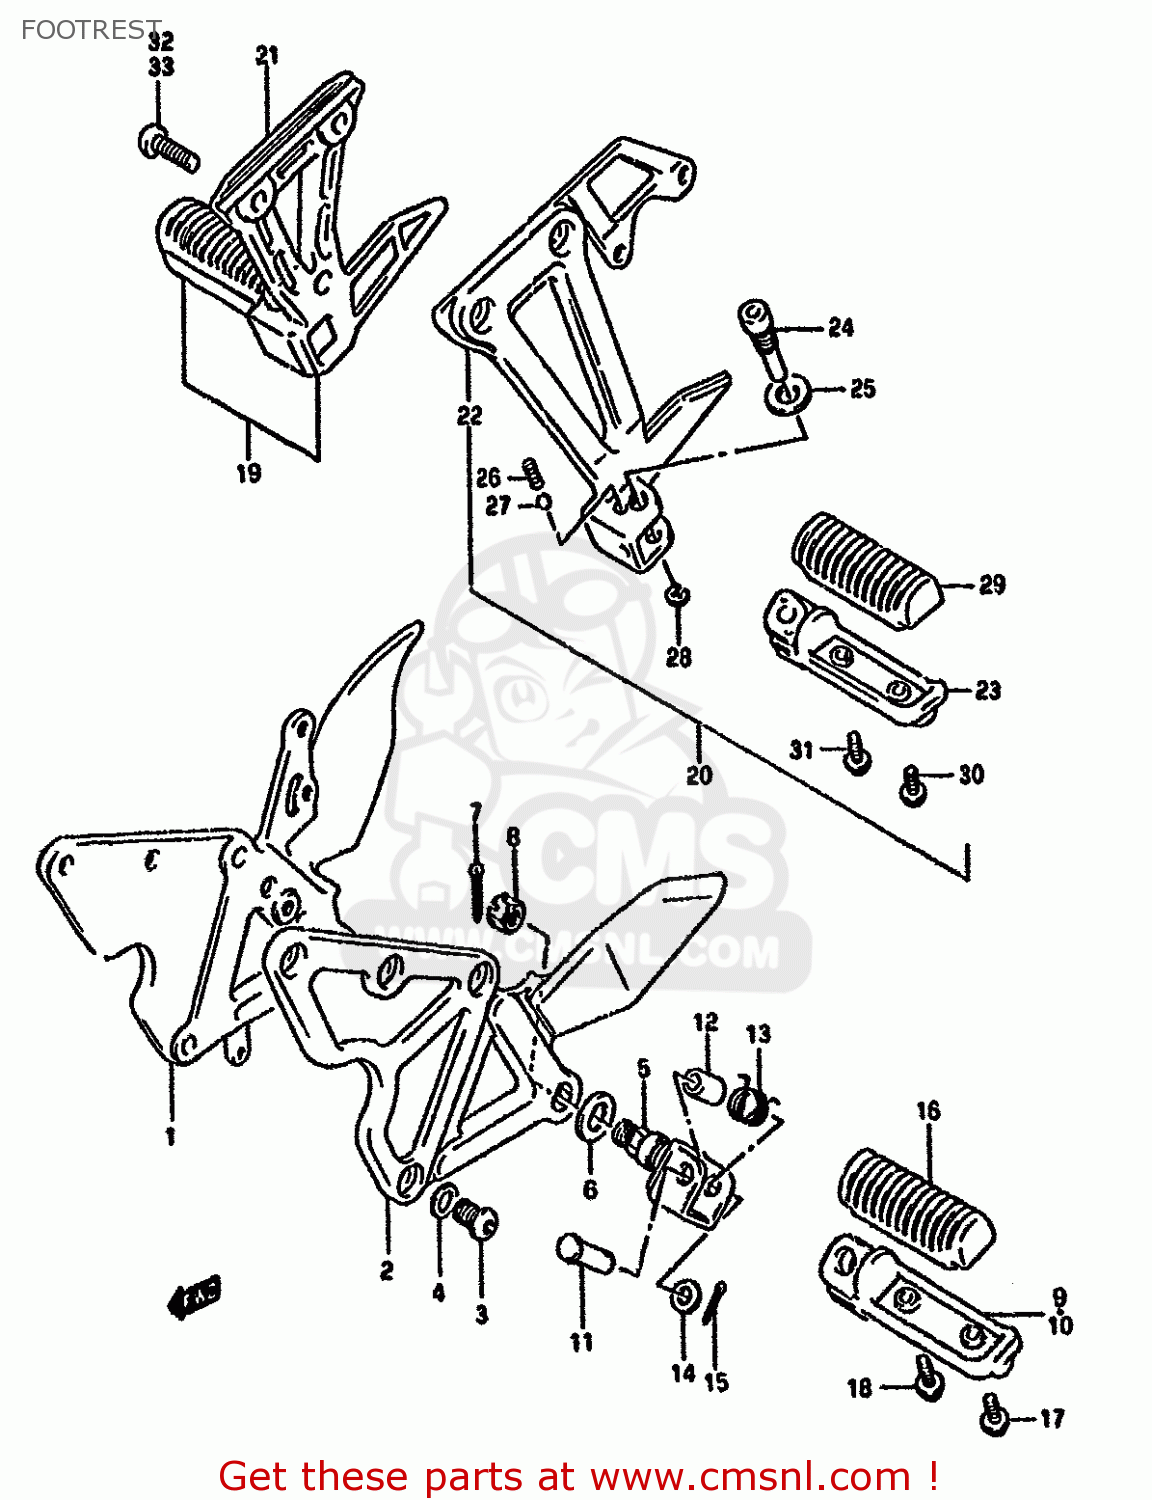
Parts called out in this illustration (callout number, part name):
1	BRACKET,FOOTREST,R
2	BRACKET,FOOTREST,L
3	BOLT
4	WASHER
5	BOSS,FR FOOTREST
6	PLATE,FOOTREST INNER
7	COTTER PIN
8	NUT, REAR AXLE
9	BAR,FOOTREST,R
10	BAR,FOOTREST,L
11	PIN
12	SPACER(8.1X12X22)
13	SPRING
14	WASHER
15	PIN 20X15
16	RUBBER,FOOTREST
17	SCREW
18	SCREW
19	FOOTREST ASSY,PILLION,R
20	FOOTREST ASSY,PILLION,L
21	BRACKET
22	BRACKET
23	BAR,PILLION FOOTREST,R
24	BOLT,PILLION FOOTREST
25	WASHER
26	SPRING
27	BALL
28	E RING
29	RUBBER,FOOTREST
30	SCREW
31	SCREW
32	BOLT
33	BOLT(8X35)
